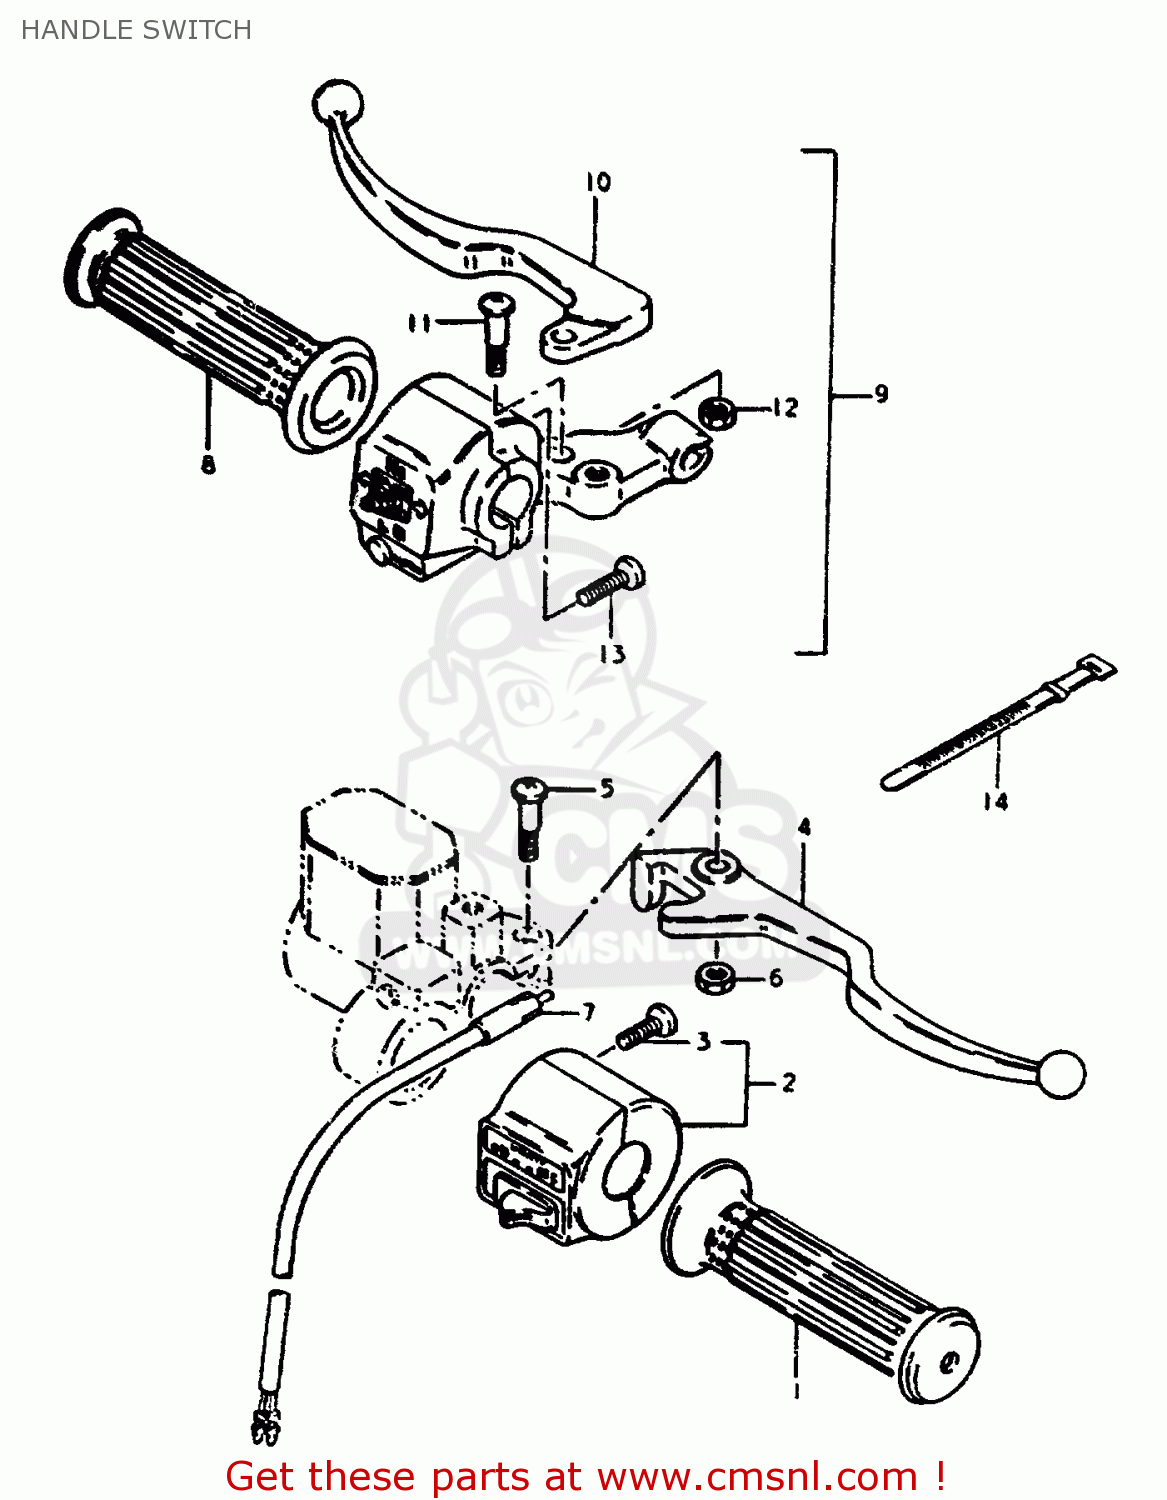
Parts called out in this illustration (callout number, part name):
1	GRIP,THROTTLE
2	SWITCH ASSY, HANDLE RH
3	SCREW 5X20
4	LEVER,BRAKE
5	SCREW
6	NUT 6MM
7	SWITCH ASSEMBLY
8	GRIP,L
9	LEVER ASSY, CLUTCH
10	LEVER,CLUTCH
11	SCREW
12	NUT,LEVER BOLT
13	SCREW 5X20
14	CLAMP(L:120)
